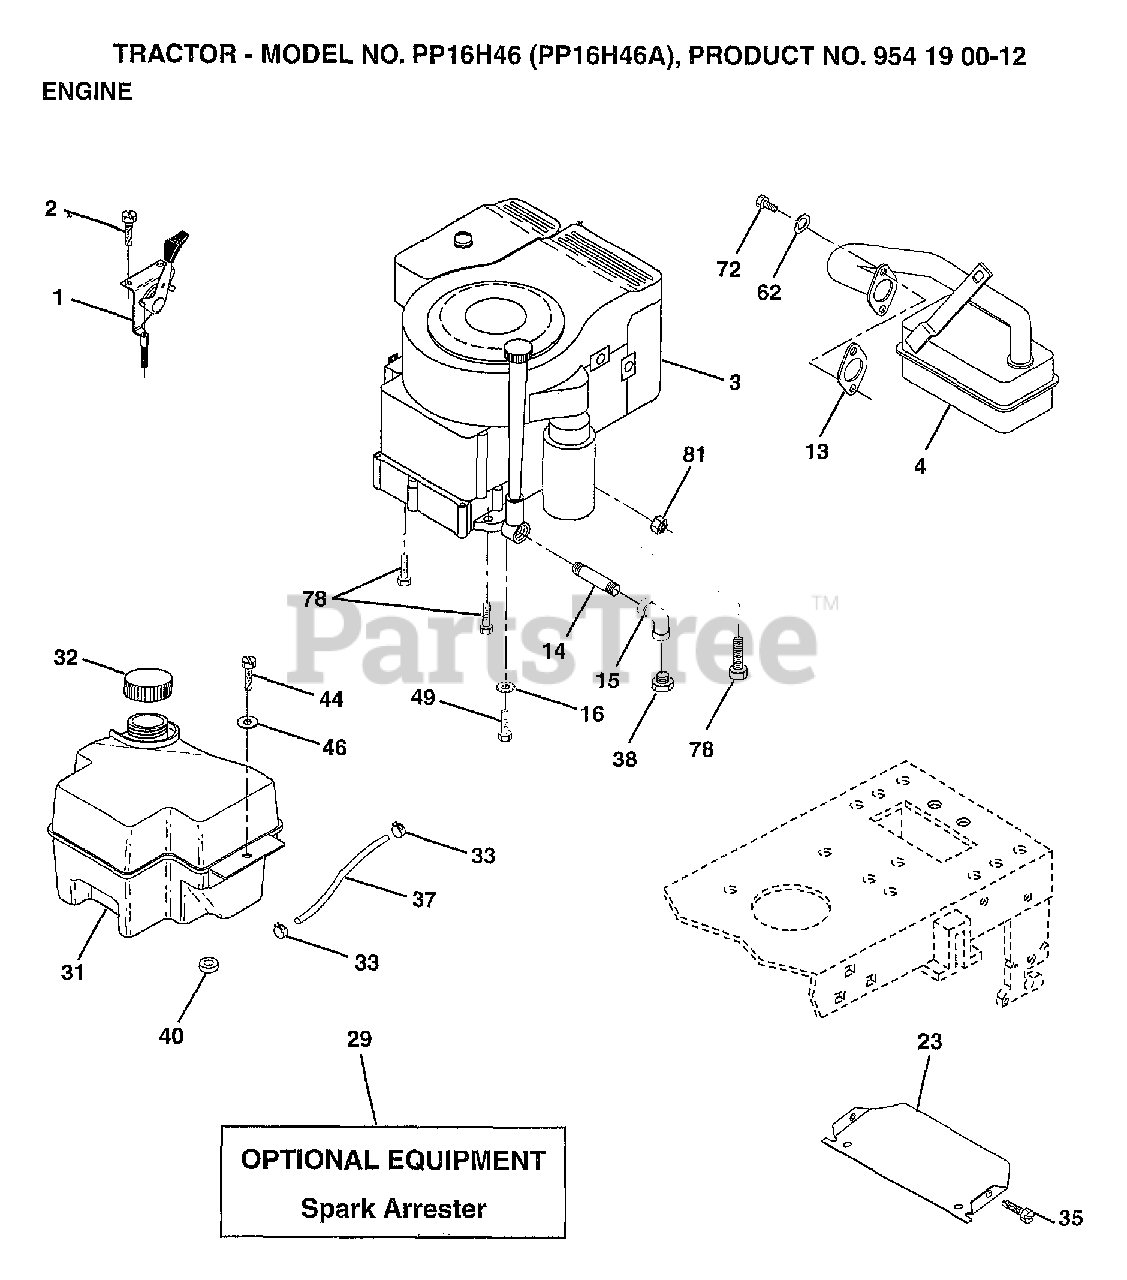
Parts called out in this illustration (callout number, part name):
1	CONTROL THROTTLE
2	SCREW LT
4	MUFFLER
13	GASKET ENG 1 313 LD TIN PLATED
14	PIPE NIPPLE
15	ELBOW
16	LOCKWASHER
23	SHIELD-HEAT
32	CAP ASM FUEL
33	HOSE CLAMP
35	SCREW
37	LINE FUEL
44	SCREW HEX CRT
46	WASHER
49	SCREW GTV
62	LOCKWASHER
72	SCREW
78	SCREW
81	NUT
